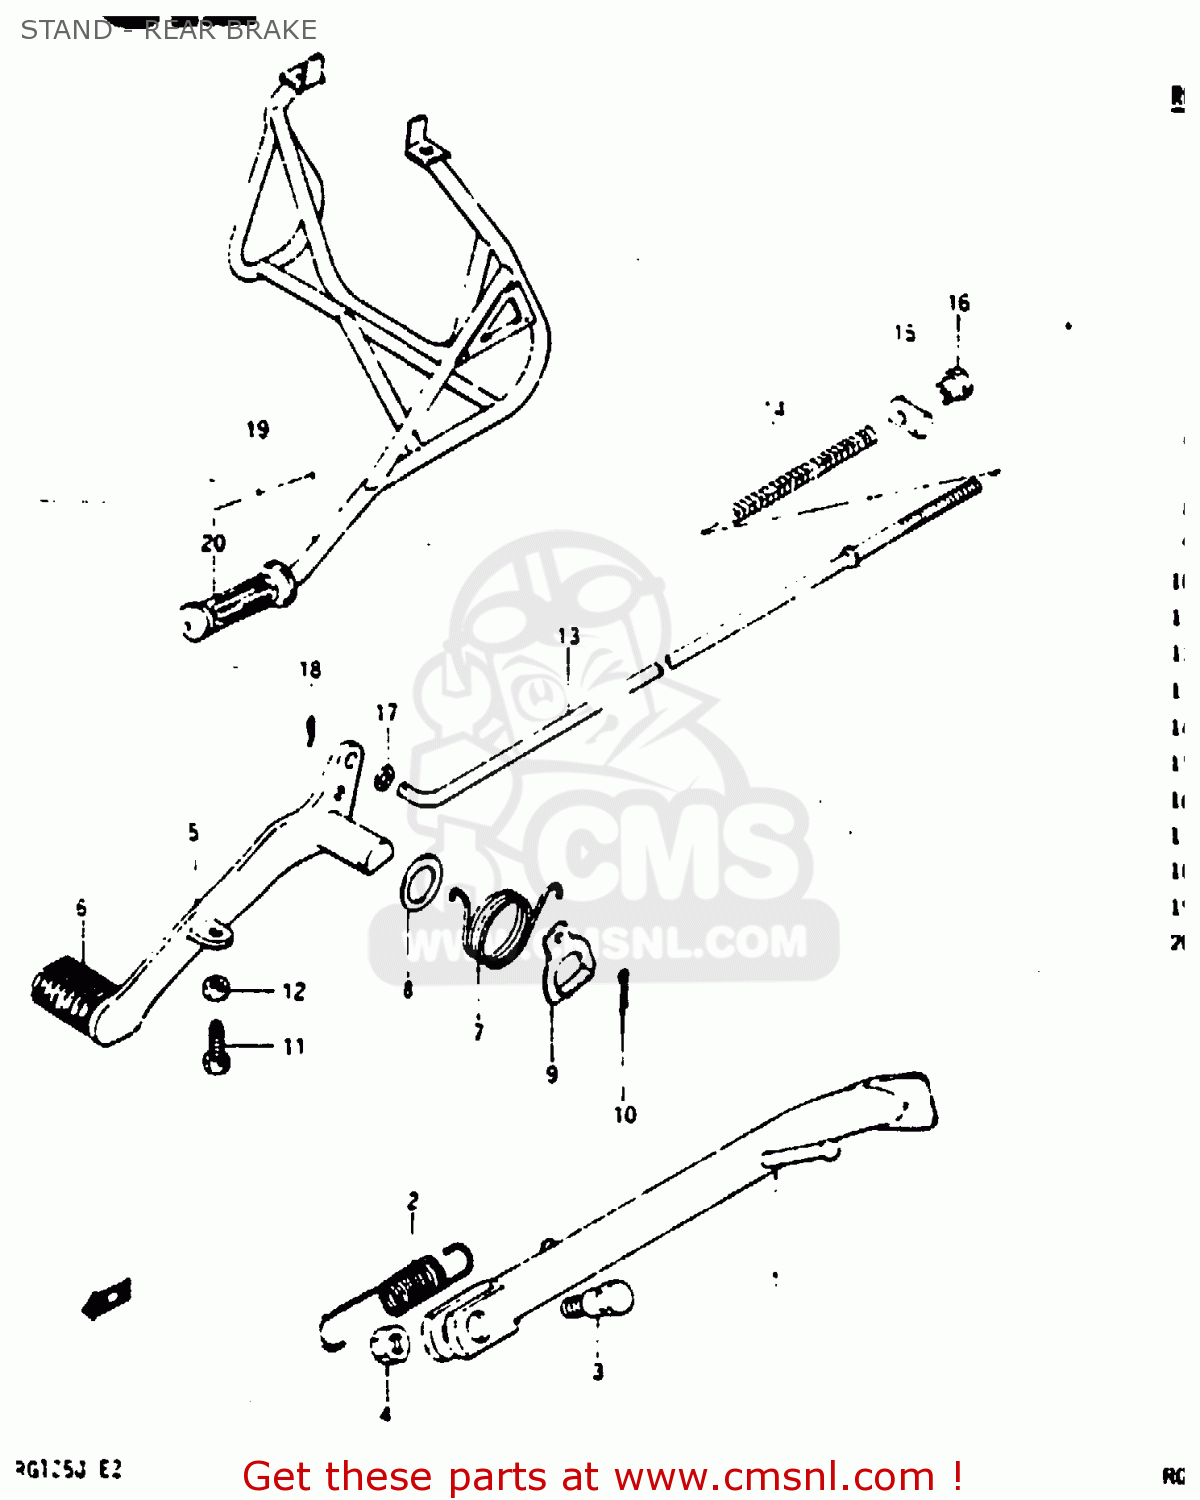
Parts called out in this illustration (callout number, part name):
1	STAND,PROP
2	SPRING
3	BOLT(10X28)
4	NUT
5	PEDAL,BRAKE
6	RUBBER,PEDAL
7	SPRING,BRAKE PEDAL RETURN
8	WASHER
9	BRACKET,STOP LAMP SWITCH
10	COTTER PIN
11	BOLT
12	NUT
13	ROD ASSY, REAR BRAKE
14	SPRING
15	PIN(11X18)
16	NUT (6MM)
17	WASHER
18	PIN
19	STAND ASSY, REAR
20	GRIP,L
